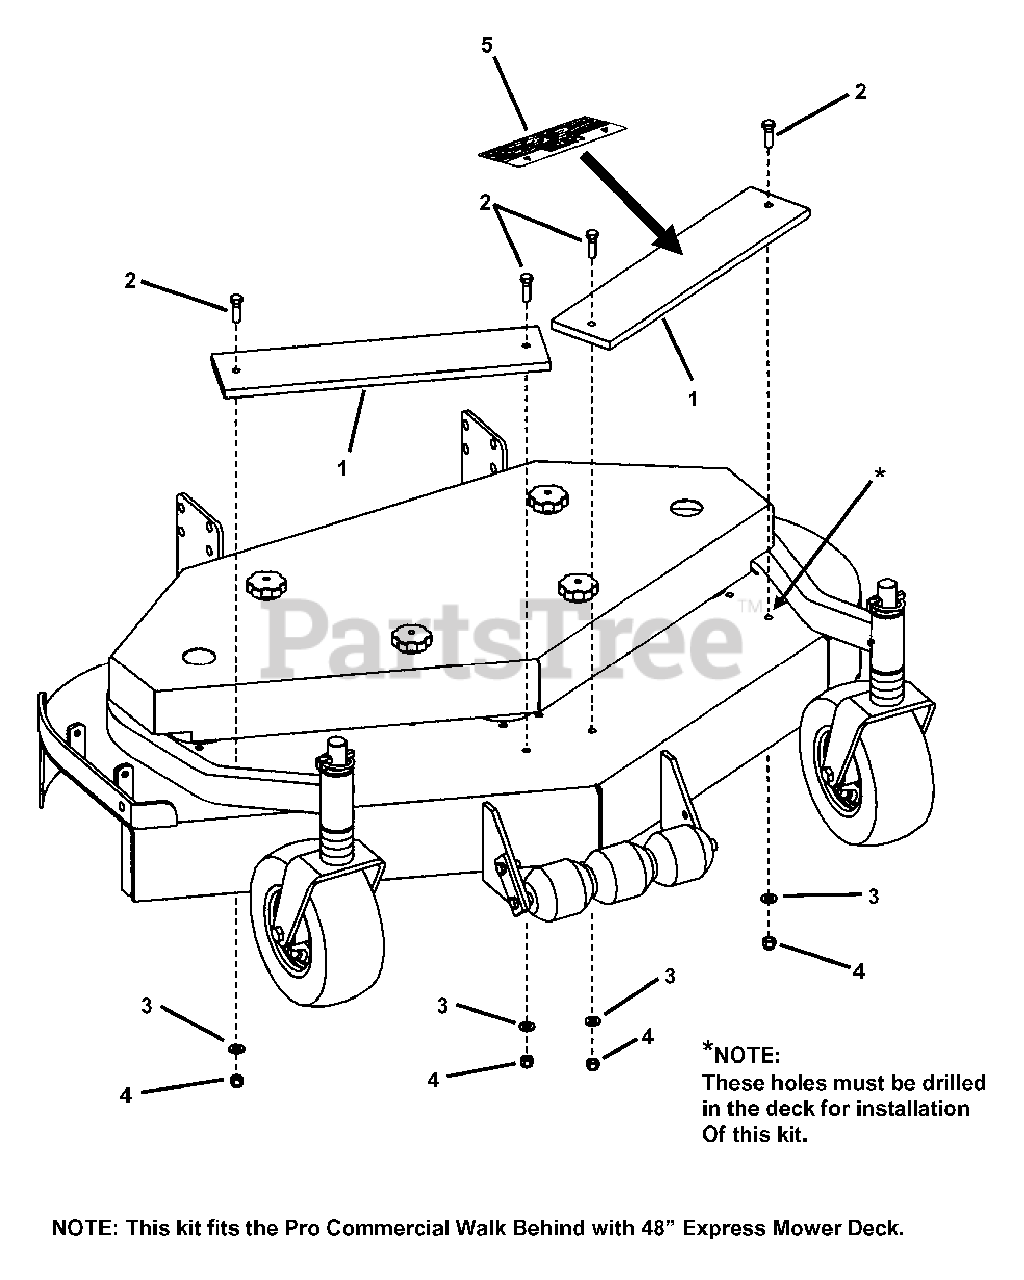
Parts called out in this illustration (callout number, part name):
1	BALLAST, 48" Express Deck
2	SCREW, 3/8-16 x 1-1/4" Hex Head Cap, Grade 5
3	WASHER, 3/8" Flat
4	NUT, 3/8-16 Nyloc
5	DECAL, Caution Guard/Catcher
